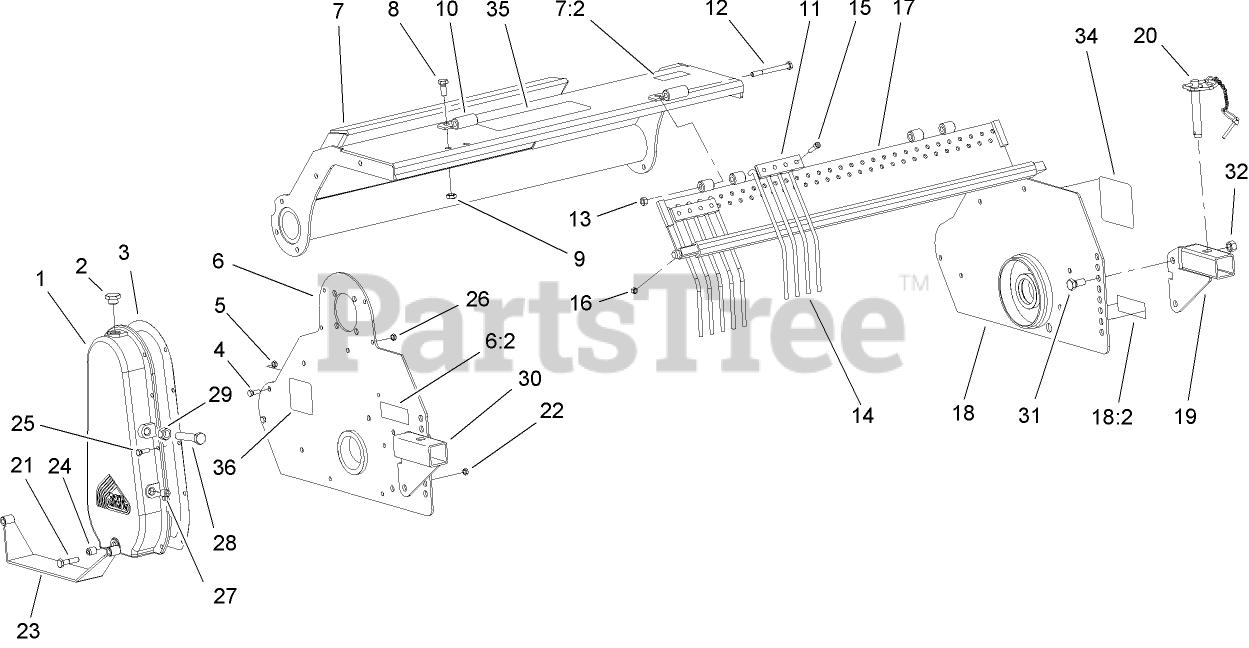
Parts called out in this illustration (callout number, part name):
1	CASE-CHAIN
3	GASKET-CORK
4	SCREW
5	NUT
6	LEFT SIDE ASM
6:2	DECAL-DANGER
7	FRAME CHASSIS ASM
7:2	DECAL-WARNING
9	NUT-LOCK
11	FLANGE
12	SCREW-HH
13	NUT
14	ROD-SCREENING
15	BOLT-HSH
16	NUT-LOCK, NI
17	PLATE-ROD, SCREENING
18	RIGHT SIDE ASM
18:2	DECAL-DANGER
19	PLATE-FITTING, RIGHT
20	PIN-DRIFT
21	SCREW
22	NUT
23	PLATE-PROTECTOR
24	PLUG-BRASS
26	NUT-LOCK, NI
27	PLUG-BRASS
28	Screw-HH
30	PLATE-FITTING, LEFT
31	SCREW-HH
32	NUT-HEX
34	DECAL
35	DECAL
36	Decal
